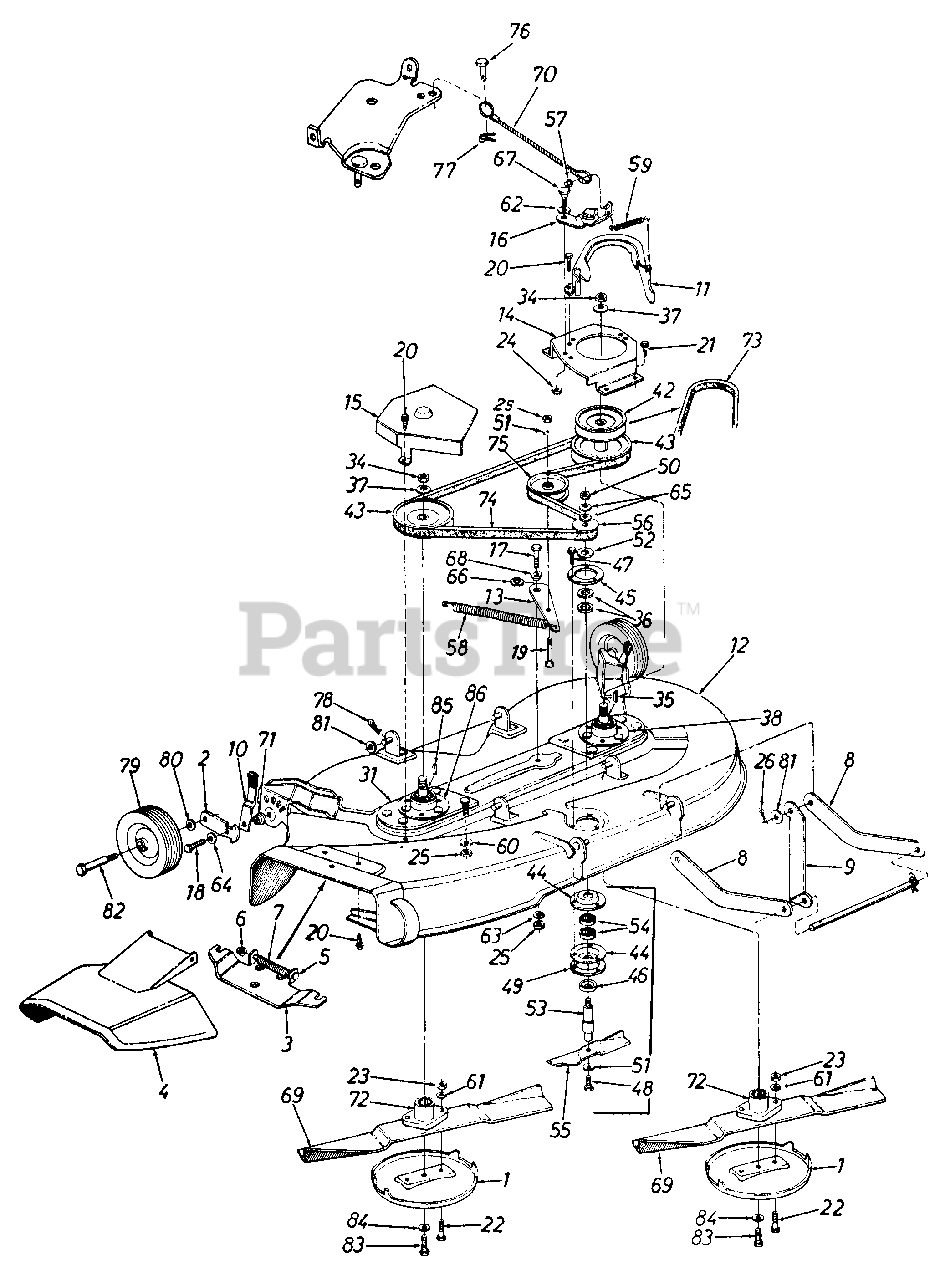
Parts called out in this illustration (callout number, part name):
1	Anti-Scalp Plate
2	Wheel Pivot Bar
3	Adapter
4	Chute Cover Ass'y.
5	Hinge Pin
6	Cap Speed Nut 1/4" Rod.
7	Torsion Spring
11	Belt Guard
12	44" Deck Ass'y.
13	Idler Bracket
14	Pulley Cover-L.H.
17	Hex Bolt 3/8-24 x 1.00"*
18	Hex Bolt 3/8-24 x 1.25"Lg.l'
19	Hex Bolt 3/8-24 x 1.50"*
20	Hex Wash. S-Tapp Scr.1/4-20 x .50"*
21	Hex Wash. Hd. Tapp Scr. 5/16-18 x .75" Lg.
22	Hex Bolt 5/16-24 x 1.25" (Grade 5)
23	Hex Nut 5/16-24 Thd.*
24	Hex Cent. L.-Nut 5/16-18 Thd.
25	Hex Nut 3/8-24 Thd.*
26	Cotter Pin 3/32 Dia. x 1.00" Lg.*
34	Hex Jam Nut 5/8-18 Thd.
35	Square Key 3/16 x 2.25" Lg.
36	Fl. Wash. 5/8" I.D. x 15/16" O.D.
37	Bell. Wash. .630 I.D. x 1.25 x .090
38	L.H. Blade Spindle Ass'y. Comp.
42	5/8 "V"Pulley .79 I.D. x 5.75 O.D.
43	"V"Pulley .79 I.D. x 6.50 O.D.
44	1-3/8" I.D.-Bearing Housing
45	Reinforcement Plate
46	Bearing Shield
47	Hex "B" Tap Scr. .250" x, 1.0" Lg.
48	Hex Cl.-Scr. 3/8-24 x .88 Lg.
49	Reinforcement Plate
50	Hex Jam Nut 1/2-20 Thd.
51	Bell.-Wash. .400 I.D. x .88 O.D. x .060
52	Fl.-Wash. .635 x 1.04 O.D. x .1 20"
53	6.5" Blade Spindle
54	Ball Brg. .62 I.D. x 1.30" O.D. x .44"
55	6.50" Blade
56	1/2" V-Pulley Half .625 I.D. x 2.25" O.D.
57	Cap Speed Nut 1/4" Rod.
58	Extension Spring .73 O.D. x 4.31 Lg.
59	Extension Spring
60	Bell.-Wash. .400 I.D. x .88 O.D. x .060
61	L.-Wash. 5/16" I.D.*
62	Spring Wash. .445 I.D. x .75 O.D. x .017
64	Bell.-Wash. .400 I.D. x 1.13 O.D. x.030
65	Bell.-Wash. .505 I.D. x 1.00 O.D. x .075
66	Spring Wash. .650 I.D. x .875 O.D. x .015 Thk.
67	Shld. Bolt .437 Dia. x .180
68	Shld. Spacer.625 I.D.
69	Mower Blade 21.88
70	Brake Cable Ass'y.
71	Shld. Spacer
72	Blade Adapter
73	"V"Belt 1/2 x 56" Lg.
74	"V"Belt 1/2 x 74" 4.
75	Fl.-Idler w/Flanges 3.50 0. D.
76	Clevis Pin 1/4 Dia. x .53 Lg.
77	Intern. Cotter Pin 5/6" Dia.
78	Intern. Cotter Pin 1/2" Dia.
79	Deck Wheel 6.0 x 1.38
80	Bell.-Wash. .400 I.D. x .88 O.D. x .060
81	Fl.-Wash. .531 I.D. x.93 O.D. x .090
82	Shoulder Bolt 3/8-16 x 1.41
83	Hex Bolt 3/8-24 x .88" Lg.
84	L.-Washer 3/8 I.D.*
85	Sq. Key 3/16 x .75" Lg.
86	R.H. Blade Spindle Ass'y. Comp.
